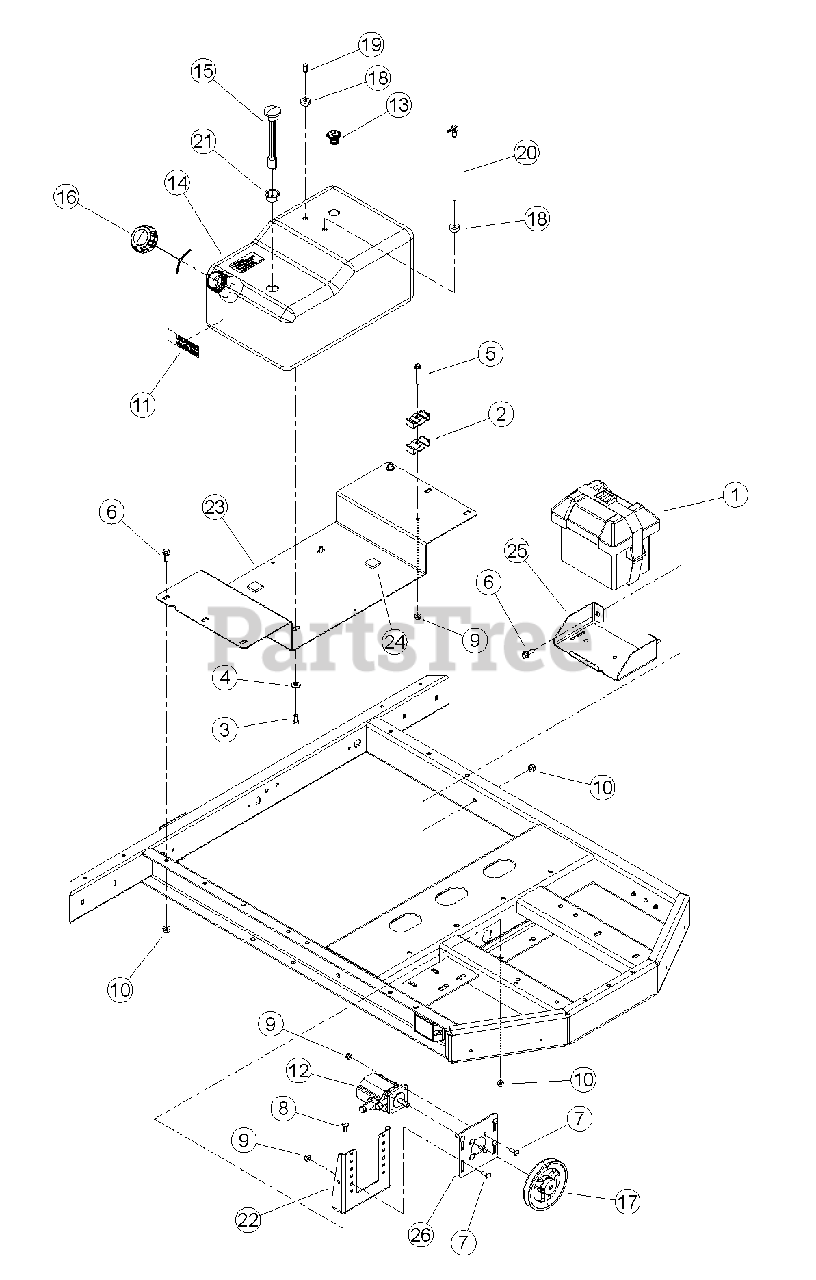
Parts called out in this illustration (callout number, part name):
1	BOX, SMALL BATTERY
2	CLAMP, PLASTIC HOSE
3	BOLT, 3/8*3/4 GR5 HEX CAPSCW ZP
4	WASHER, 3/8" FLAT ZP
5	BOLT, 5/16 X 2-1/4 FLANGE NC
6	BOLT, 3/8 X 1 FLANGE NC
7	BOLT, 5/16" X 1" GR5 CRG ZP
8	BOLT, CARR 5/16*7/8" GR5 NC ZP
9	NUT, 5/16-18 NYLOCK-FLANGE
10	NUT, 3/8-16 NYLOCK FLANGE
11	DECAL, UNLEADED GASOLINE
12	PUMP, 2 STAGE CW HI/LO 0.605 DISP.
13	VALVE, ROLL OVER
14	TANK, ROTOMOLDED FUEL
15	GAUGE, FUEL LEVEL KELCH 100
16	CAP, NON-VENTED EPA/CARB APPROVED
17	FHP B PULLEY, 5.6 - 1/2" BORE
18	GROMMET, TANK FITTING
19	PLUG, TANK VENT
20	FITTING, TANK FUEL PICK-UP TUBE
21	GROMMET, KELCH 100 GAUGE
22	BRACKET, MOUNT HYDRAULIC PUMP
23	BASE, 9.25 GAL NYLON TANK
24	PAD, FOAM FUEL TANK DAMPER
25	BRACKET, BATTERY HOLDER
26	PLATE, HYDRAULIC PUMP
